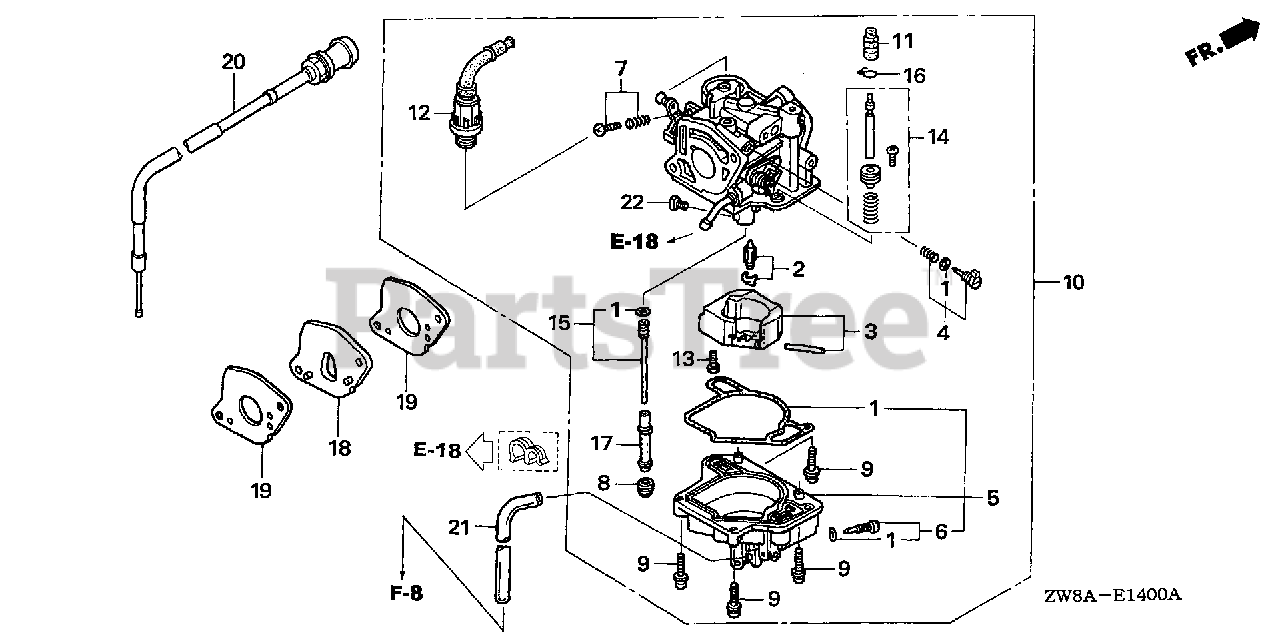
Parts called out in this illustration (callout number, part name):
1	GASKET SET
2	VALVE SET, FLOAT
5	CHAMBER SET, FLOAT
6	SCREW SET, DRAIN
7	SCREW SET
8	SCREW, PLUG
9	SCREW-WASHER
10	CARBURETOR ASSY. (BJ05A D)
12	VALVE SET, STARTER
13	SCREW, PAN
14	PLUNGER SET, ACCELERATOR PUMP
15	JET SET (#45)
16	CLIP, TUBE
17	NOZZLE, MAIN
18	INSULATOR, CARBURETOR
19	GASKET, CARBURETOR
20	CABLE, CHOKE
21	BULK HOSE, VINYL (4X7X8000) (4X7X200)
22	JET, MAIN (#100)
22	JET, MAIN (#102)
22	JET, MAIN (#105)
